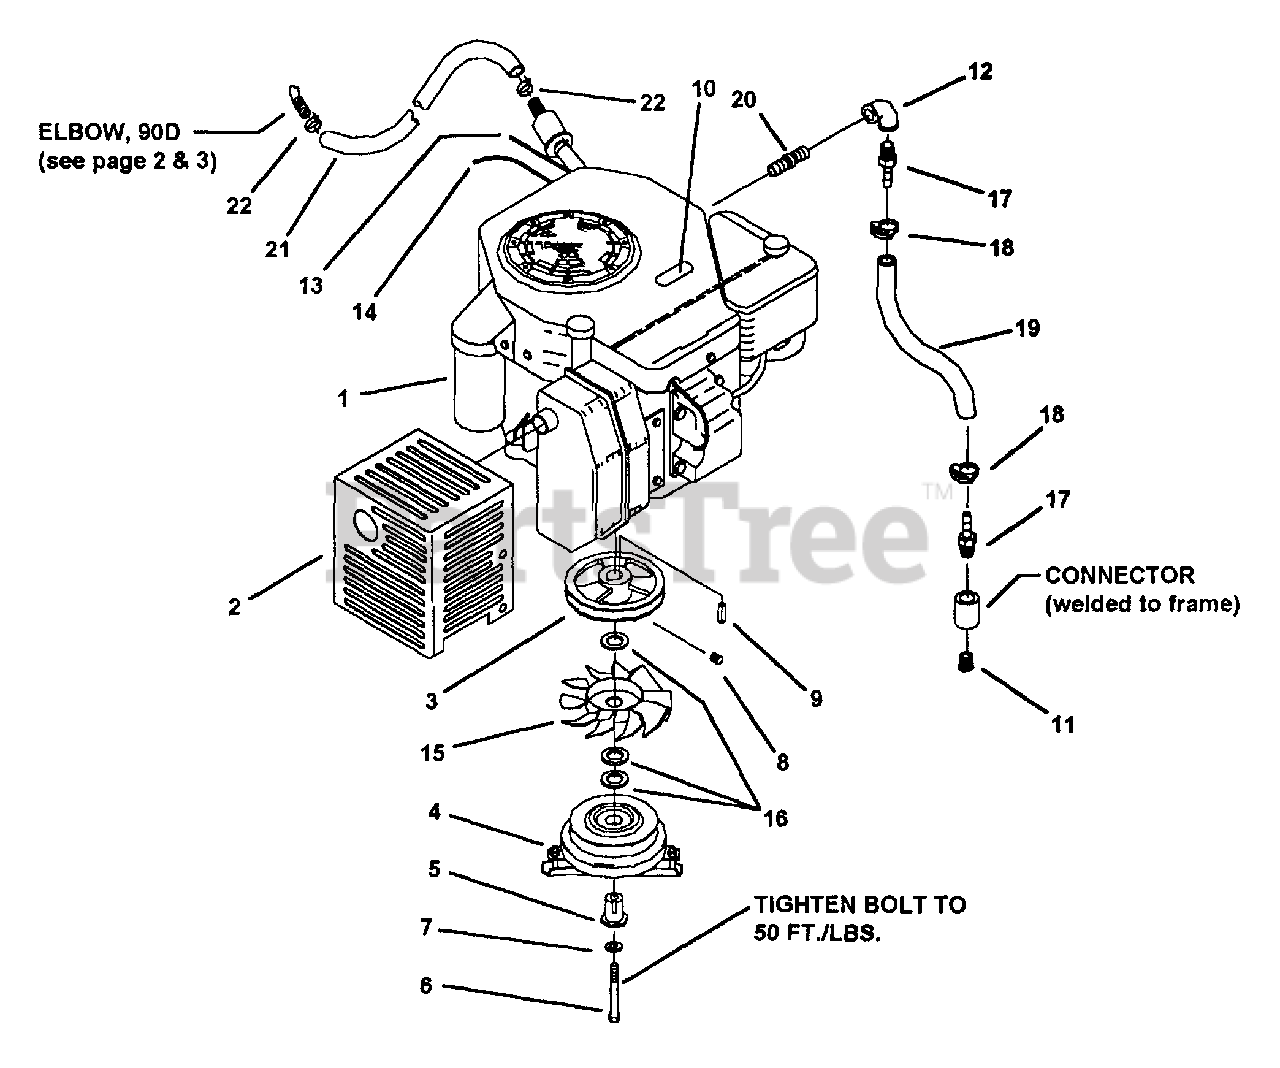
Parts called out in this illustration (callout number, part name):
1	ENGINE, 14 HP KOHLER COMMAND
2	MUFFLER GUARD WELDMENT, KOHLER
3	PULLEY, MOTOR DRIVE
4	CLUTCH, ELECTRIC, 1" BORE
5	BUSHING, CLUTCH
6	CAPSCREW, HEX HD. 10M-1.5 X 90MM
7	LOCKWASHER, 7/16" SPLIT SPRING
8	SETSCREW, SOCKET HD. 5/16-18 X 3/8"
9	KEY, 1/4" SQ. X 1"
10	DECAL, "PERIODICALLY CLEAN"
11	PLUG, PIPE 3/8"
12	ELBOW, 3/8". 90D, SCH. 40, CAST IRON
13	CABLE, THROTTLE & 14HP
14	CABLE, CHOKE 12HP & 14HP
15	FAN, 7" DIA. 10 BLADE CW
16	WASHER, SHIM
17	HOSE BARB, 3/8" HOSE X 3/8" NPT
18	HOSE CLAMP, 19/32-21/32, NYLON
19	OIL HOSE, 7-1/2" LONG
20	NIPPLE, 3/8" CLOSE SCH. 40
21	FUEL HOSE, 24"
22	CLAMP, HOSE SPRING TYPE 1/2" O.D.
